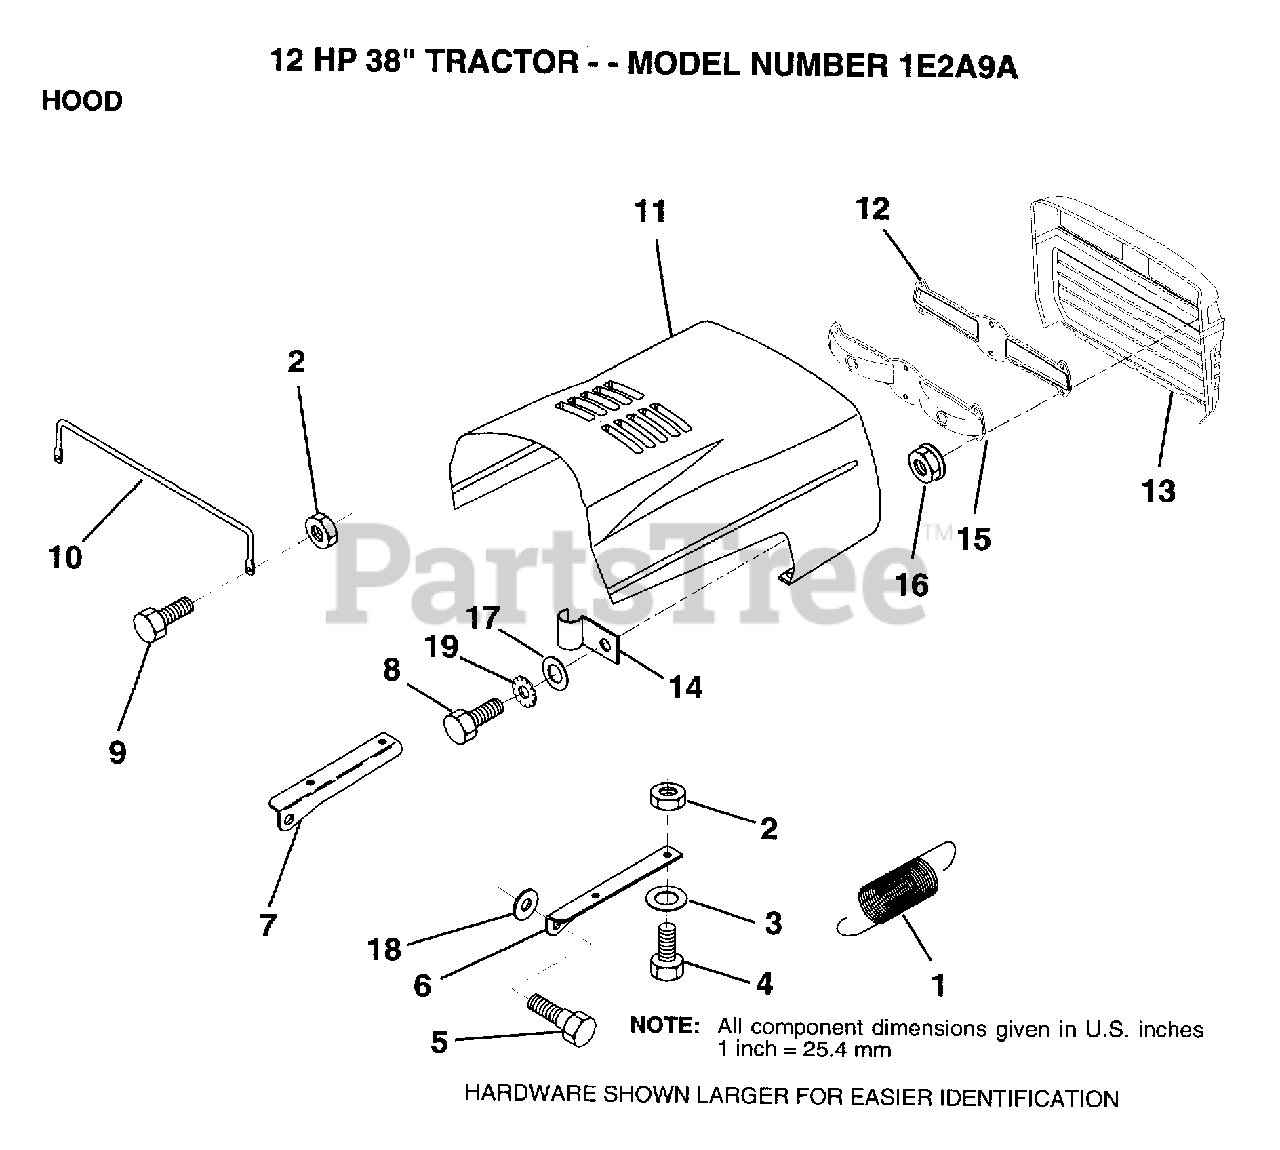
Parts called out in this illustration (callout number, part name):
1	EXT SPRING
2	NUT
3	WASHER
4	BOLT
6	BRKT HOOD RH
7	BRKT HOOD LH
10	"BRACE,HOOD"
11	HOOD
13	GRILL (BLACK)
14	CLIP T
16	NUT
17	WASHER
18	WASHER
19	LOCKWASHER GT
